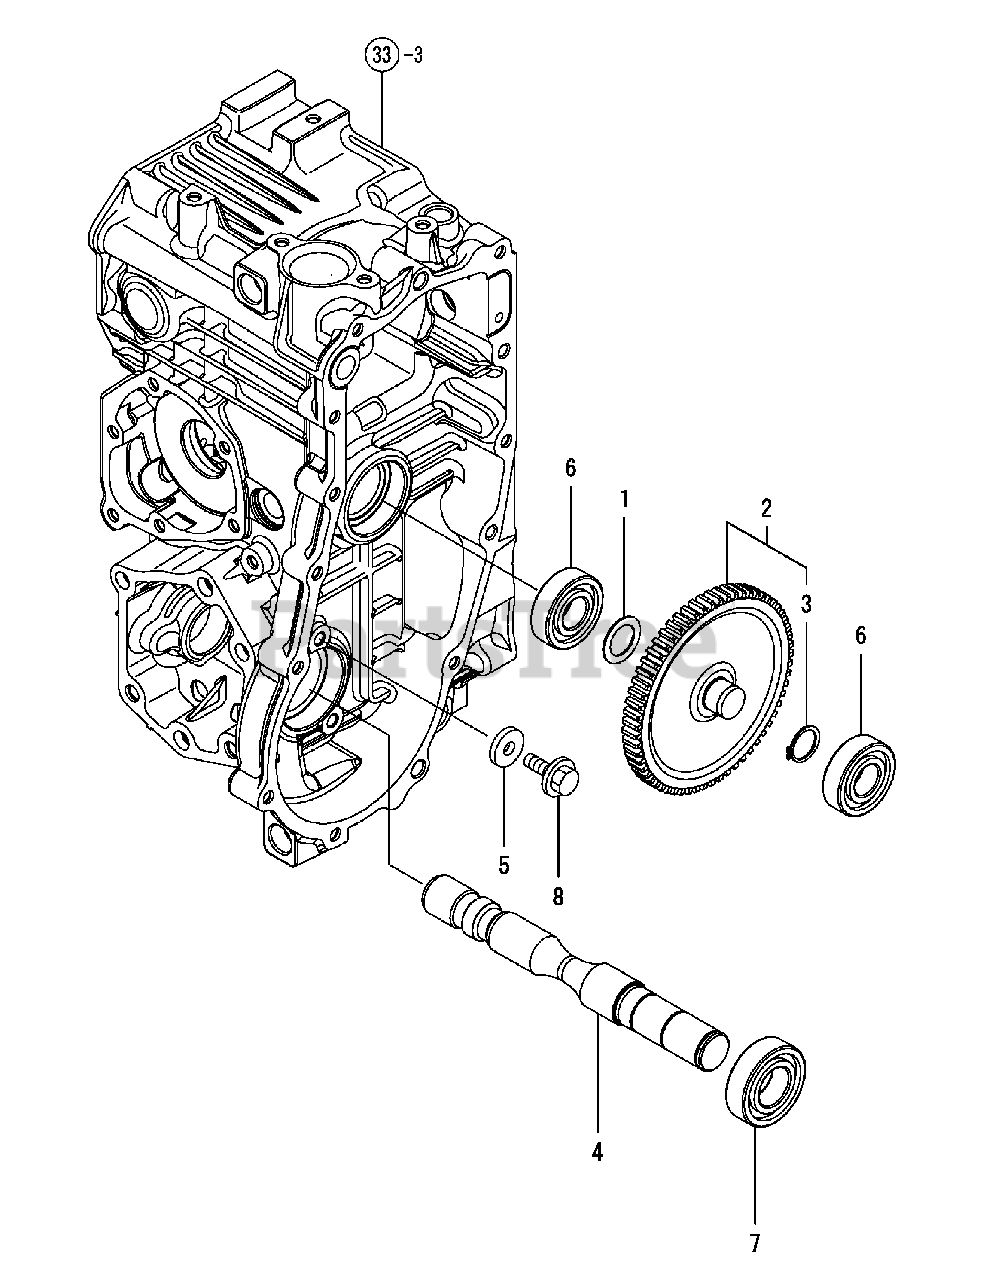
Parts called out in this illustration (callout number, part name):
2	IDLE ASSY, PTO
4	SHAFT, MID PTO
5	WASHER, 8.5X24X4
6	BALL BEARING #6204
